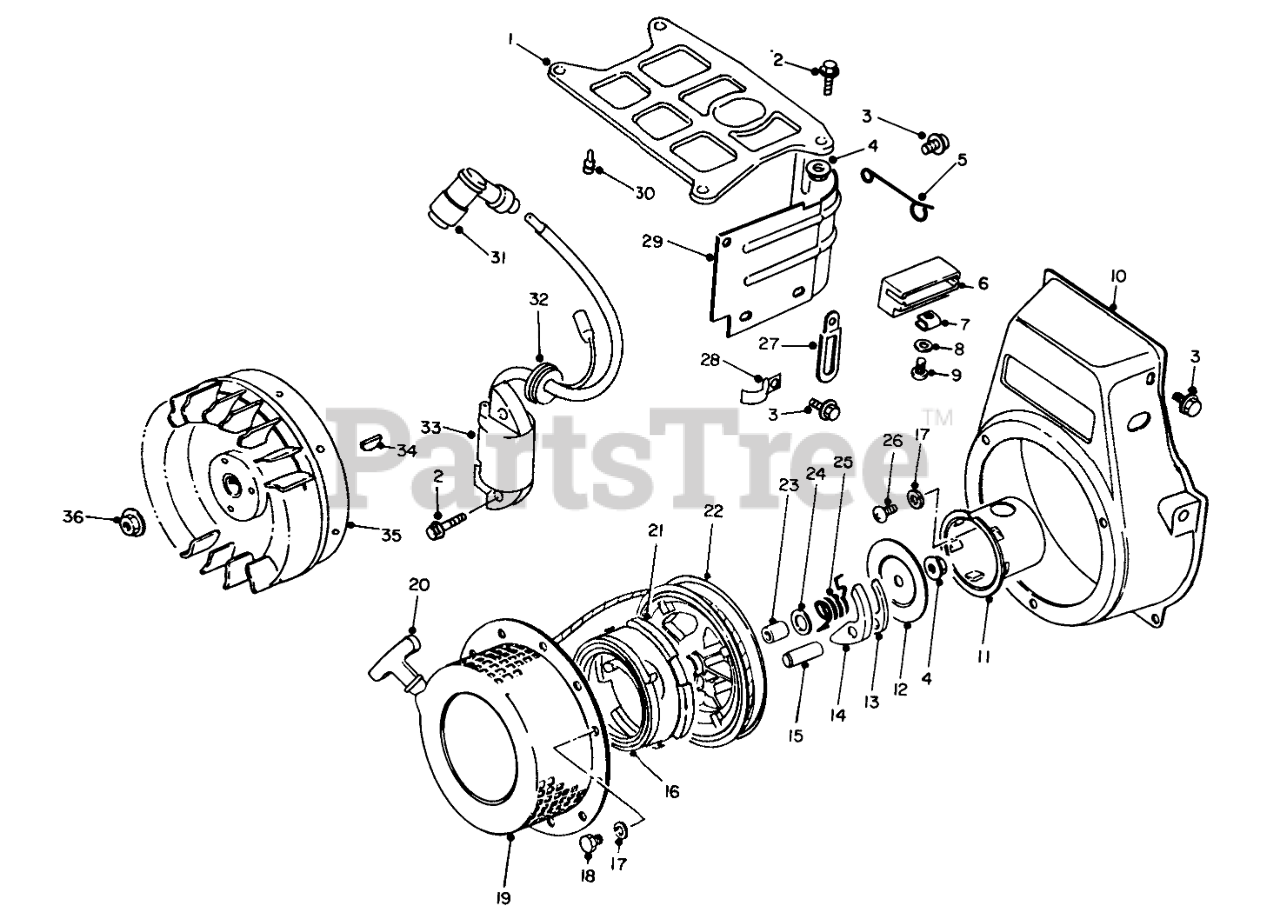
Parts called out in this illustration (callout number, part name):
3	Rotor
5	STATOR
6	Grommet
7	SPARK PLUG CAP
8	COWLING
9	Cushion
10	Cowling-Upper
13	CLAMP
14	CLAMP
15	Clamp
17	Washer
19	Holder-Lead Connector
20	COVER
21	Pulley-Starter
23	Plate-Friction
24	Ratchet
25	Ratchet
27	Spring-Spiral
28	LOCKWASHER
30	Starter Assembly Recoil (Incl. Ref. #22-29 & 31-37)
31	Grip Assembly (Incl. Ref. #32)
32	Grip
33	SPRING CASE
35	Spacer
36	Washer
37	Spring-Friction
38	Screw
